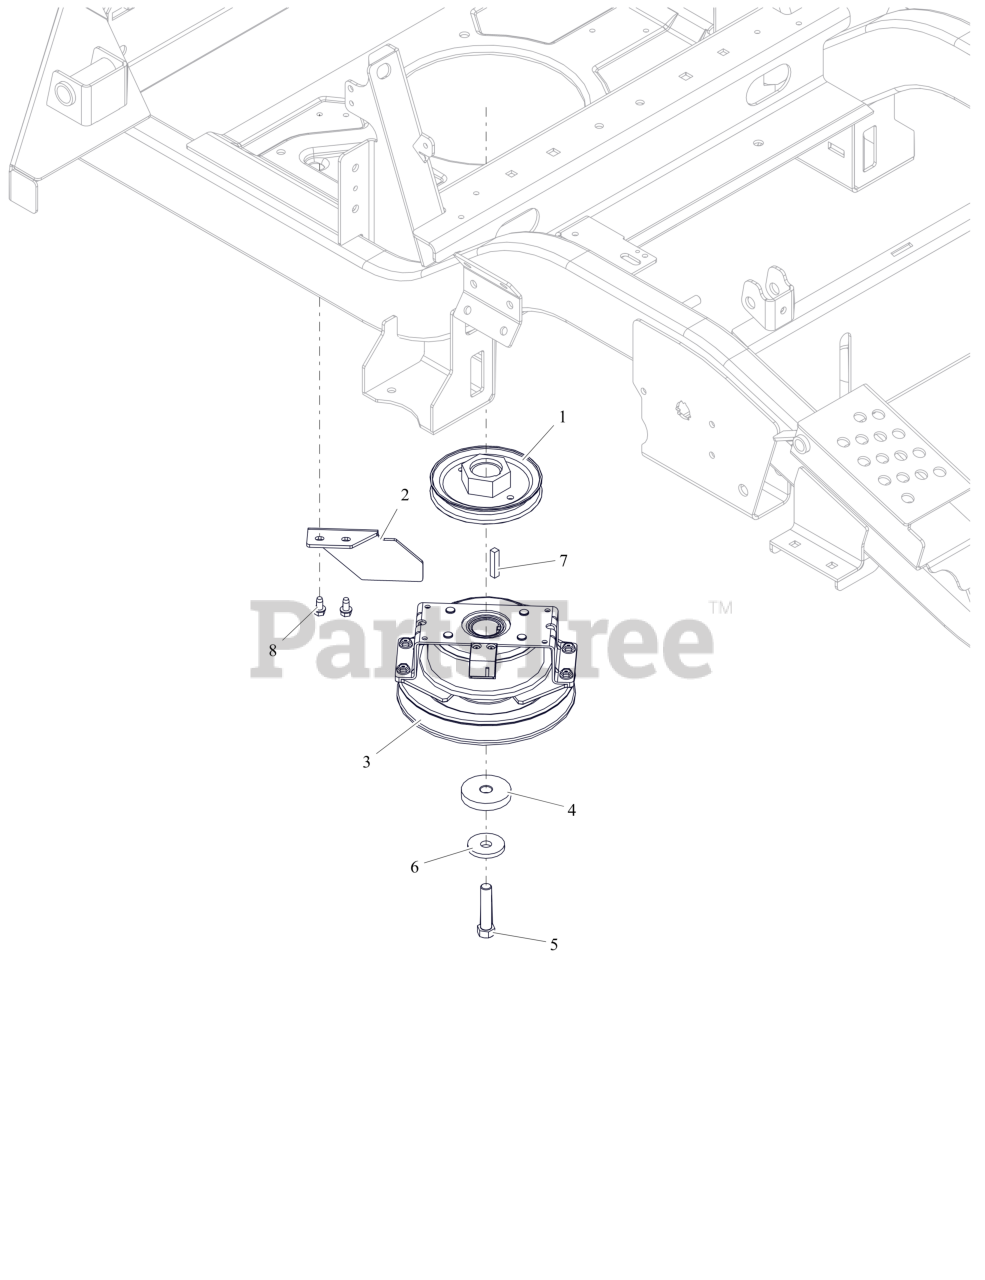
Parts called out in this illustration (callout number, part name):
1	WLDMT,PULLEY-4.50ODX1.127
2	BRKT, CLUTCH STOP HD
3	CLUTCH, OGURA DBL SPRG
4	SPACER, .474/.459X2.00X.350
5	BLT, HEX 0.4375-20X2 G8 ZCC NT
6	WASHER, 7/16" SPRING DISK
7	KEY-SQ .25 X 1.25 X .25 SAE
8	SCR-TAP .25-20X.50 HWH ZCC
